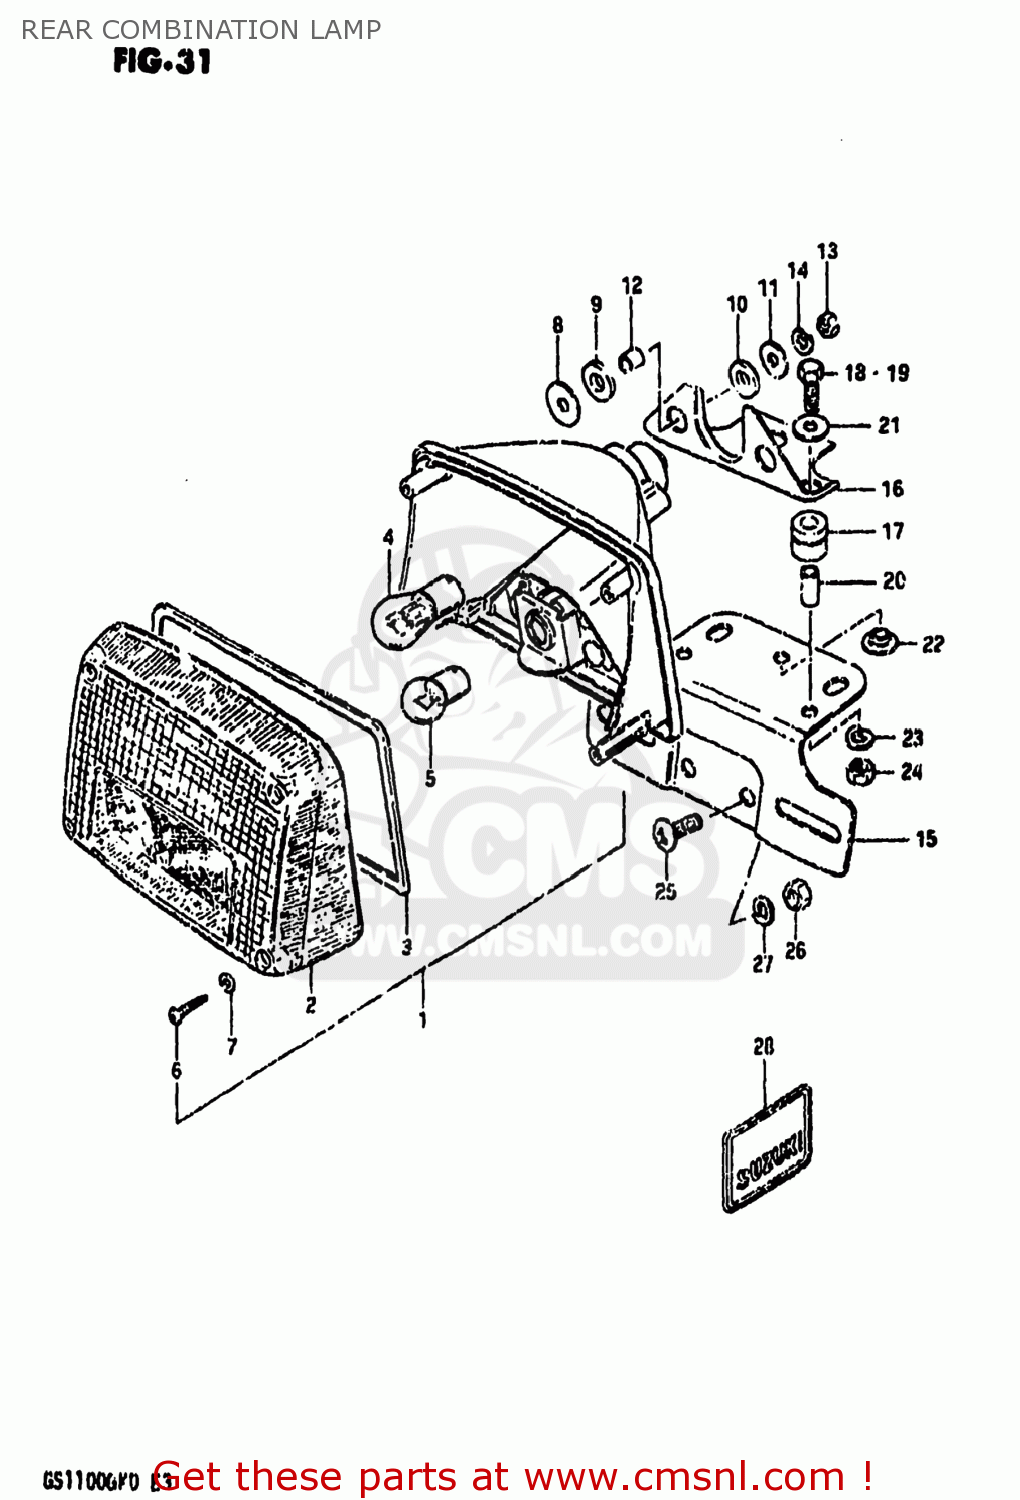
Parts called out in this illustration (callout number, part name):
1	LAMP ASSEMBLY,REAR COMBINATION
2	LENS
3	GASKET (NAS)
4	BULB(12V23W)
5	BULB
6	SCREW,REAR COMBINATION LAMP
7	GASKET (NAS)
8	WASHER
9	CUSHION
10	CUSHION
11	WASHER(6,5X22X1.6)
12	SPACER(6.1X9X7.5)
13	NUT
14	LOCK WASHER
15	PLATE,REAR LICENSE
16	BRACKET,LICENSE PLATE
17	CUSHION, BRACKET
18	BOLT
19	BOLT
20	SPACER (6.4X9X15.5)
21	WASHER
22	WASHER
23	LOCK WASHER
24	NUT
25	SCREW
26	NUT
27	LOCK WASHER
28	EMBLEM,SEAT TAIL COVER
